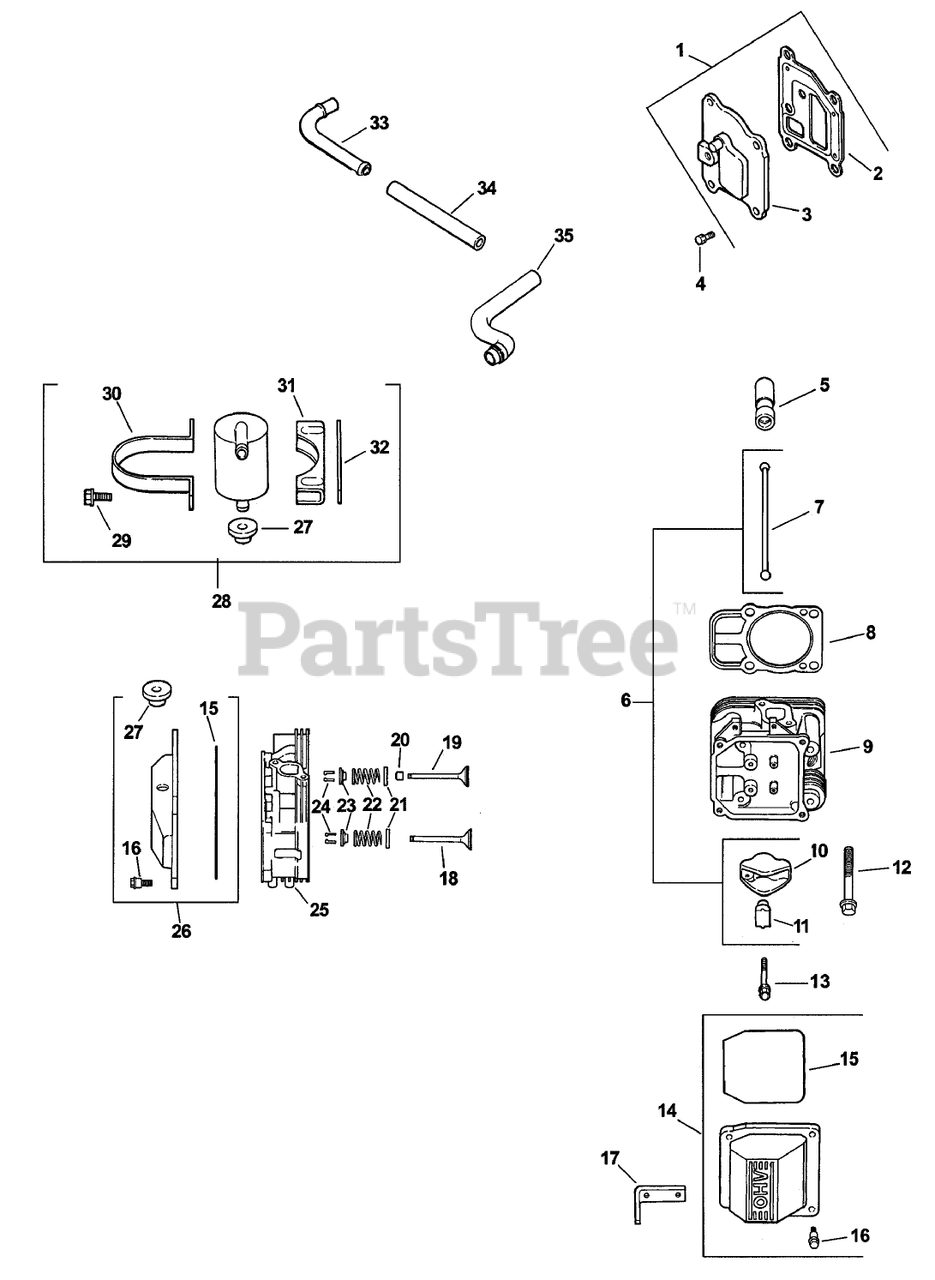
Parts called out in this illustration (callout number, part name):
1	Kit, breather cover w/gasket (Incl. 2,3)
2	Gasket-Breather
3	Cover, breather
4	Screw
5	Lifter-Valve
6	Kit, valve train (Includes 7,10,11)
7	ROD-PUSH
8	Gasket-Cylinder Head
9	Head assembly, #2 cylinder
10	ARM-ROCKER
11	Pivot-Arm, Rocker
12	SCREW-FLANGE (M10X1.5X90)
13	Screw
14	Kit, valve cover-plain (Includes 15,16)
15	O-Ring
16	Screw-Shoulder (M6x1.0x30)
17	STRAP-LIFTING
18	VALVE-EXHAUST (STD)
19	VALVE-INTAKE (STD)
20	Seal-Stem, Valve
21	RETAINER-SPRING
22	SPRING-VALVE
23	CAP-SPRING, VALVE
24	RETAINER KIT
25	Head assembly, #1 cylinder
26	Kit,valve coverbreather(Incl. 15,16,27)
27	Grommet, rubber
28	Kit, breather separator (Includes 27,29-32)
29	Screw, hex. flange
30	STRAP-BREATHER
31	BRACKET-SEPARATOR, BREATHER
32	Spacer
33	Fitting
34	Hose, breather
35	Hose, breather
